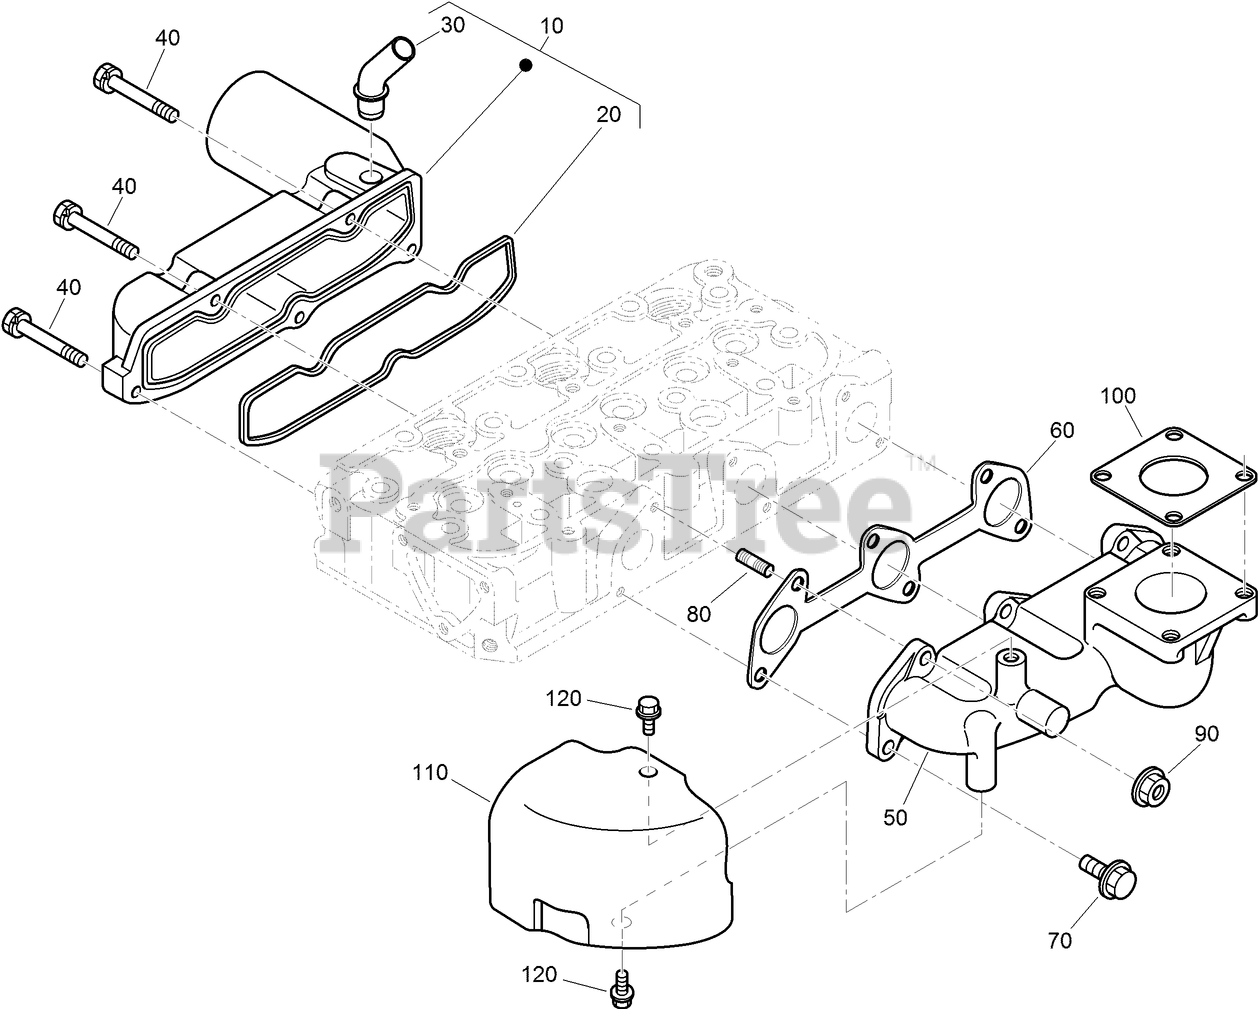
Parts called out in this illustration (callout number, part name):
10	INTAKE MANIFOLD ASM
20	GASKET-MANIFOLD, INTAKE
30	PIPE-BREATHER
50	MANIFOLD-EXHAUST
60	GASKET-MANIFOLD, EXHAUST
70	SCREW-HEX HD
80	BOLT-STUD
100	GASKET-MUFFLER
110	COVER-HEAT
120	SCREW-FLANGE HD
